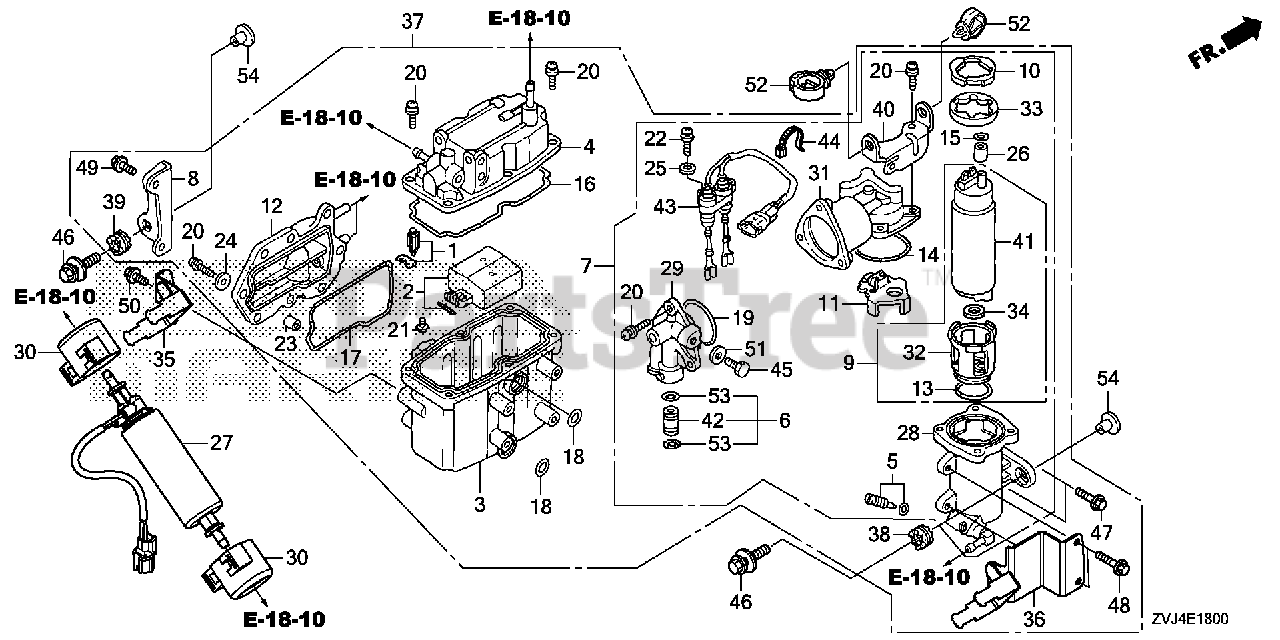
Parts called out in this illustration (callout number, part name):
1	VALVE SET, FLOAT
5	SCREW SET, DRAIN (CARBURETOR NO.)
7	PUMP UNIT SET A, FUEL
8	STAY, PLATE
9	PUMP UNIT SET B, FUEL (MSDS)
12	COVER, WATER JACKET
15	O-RING
15	O-RING (7.3X2.2) (NOK)
20	SCREW-WASHER
21	SCREW, PAN
22	SCREW, WASHER
23	COLLAR, SET
24	WASHER, PLAIN
25	WASHER, PLAIN
27	PUMP ASSY., FUEL
28	CASE, PUMP
29	COVER, PUMP
30	RUBBER, FUEL PUMP
31	COVER, PUMP (A)
35	STAY A, FUEL PUMP
36	STAY B, FUEL PUMP
37	SEPARATOR ASSY., VAPOR
38	GROMMET, VAPOR SEPARATOR
39	GROMMET, VAPOR SEPARATOR
40	STAY, PLATE
41	PUMP UNIT, FUEL (MSDS)
42	JOINT, FUEL PIPE
45	BOLT, SEALING (6MM)
46	BOLT-WASHER (8X35)
47	BOLT, FLANGE (6X25)
48	BOLT, FLANGE (6X28)
49	BOLT, FLANGE (6X16)
50	BOLT, FLANGE (6X14)
51	WASHER, SEALING (6MM)
52	CLIP, HARNESS
53	O-RING (7.8X1.9) (ARAI)
54	COLLAR (8.5X14.5)
